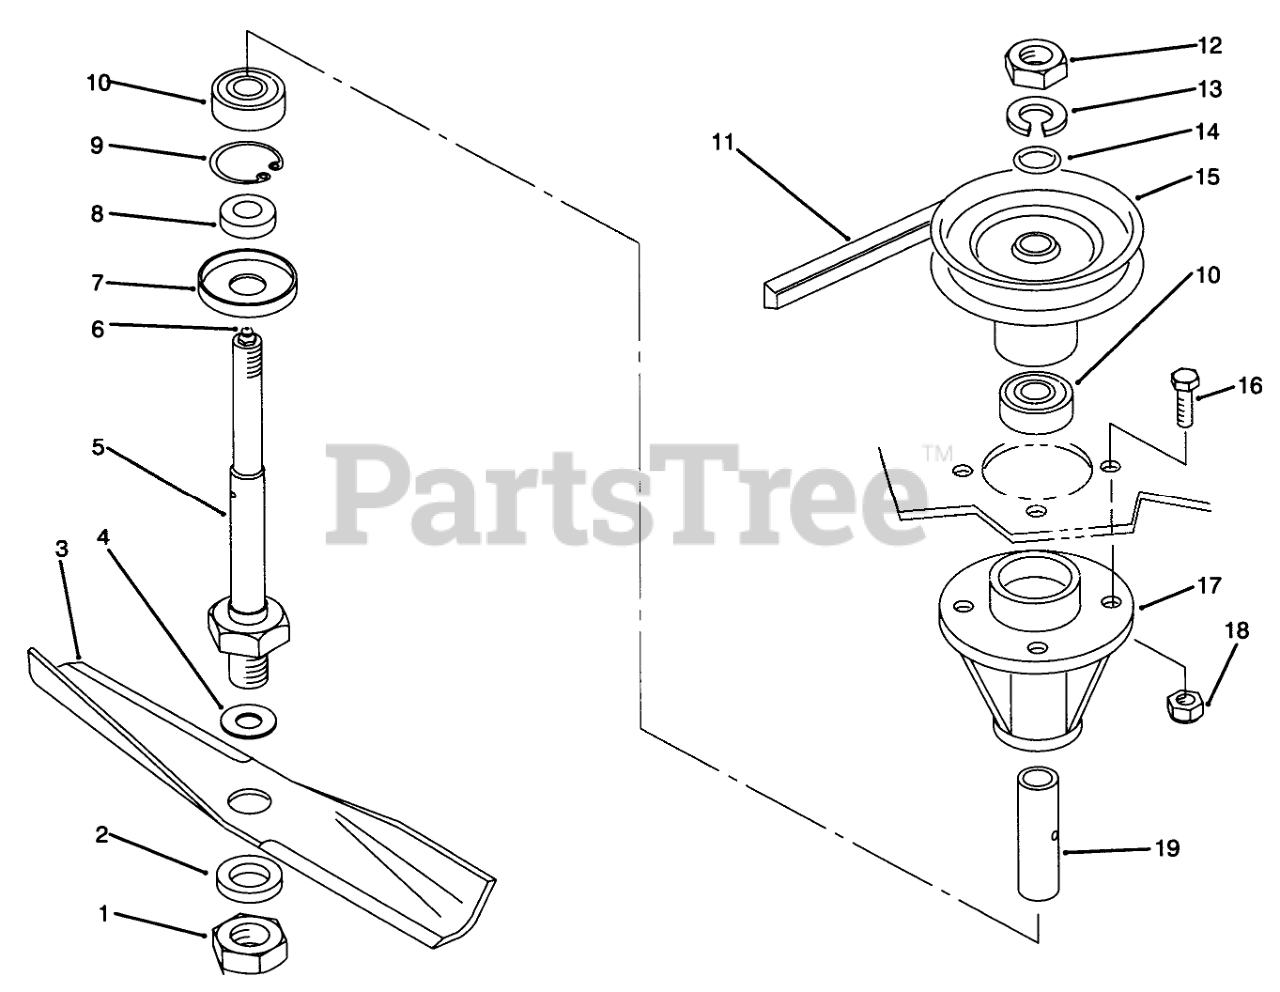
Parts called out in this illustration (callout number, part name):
1	NUT-JAM
2	WASHER-FLAT
3	14IN BLADE KIT
4	Washer
5	SHAFT-SPINDLE
6	FITTING-GREASE
7	CUP-SPINDLE
8	SPACER-BLADE
9	RING-RETAINING
10	BEARING-BALL
11	Belt
12	NUT-JAM
13	WASHER-LOCK
14	O RING
15	Pulley-Spindle
16	Bolt
17	HOUSING-SPINDLE
18	NUT-LOCK, NI
